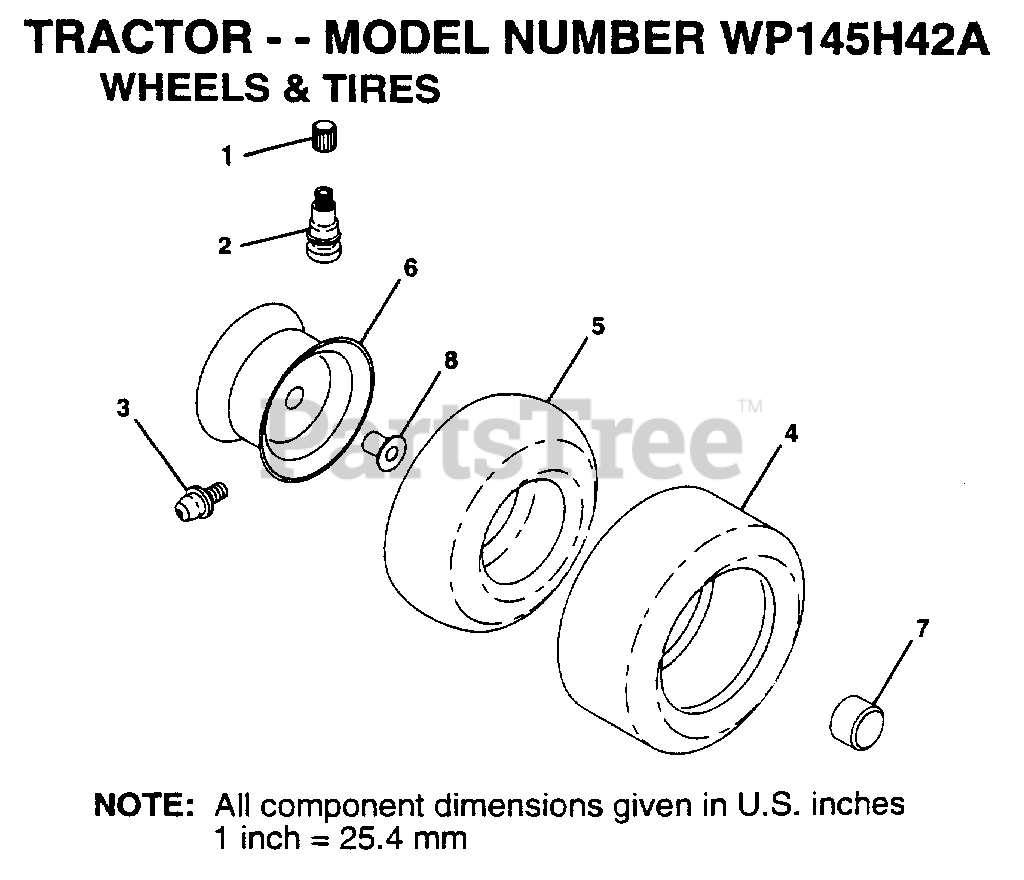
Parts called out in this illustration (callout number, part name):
1	VALVE CAP
2	VALVE STEM LT
3	FITTING LT
4	TIRE.20X8-8
5	TUBE.5.3/4.5/6
5	TUBE.18X9.5-8
6	"RIM,FRT T"
6	"RIM 8"""
7	HUB CAP
8	"FLANGE, BEARING"
